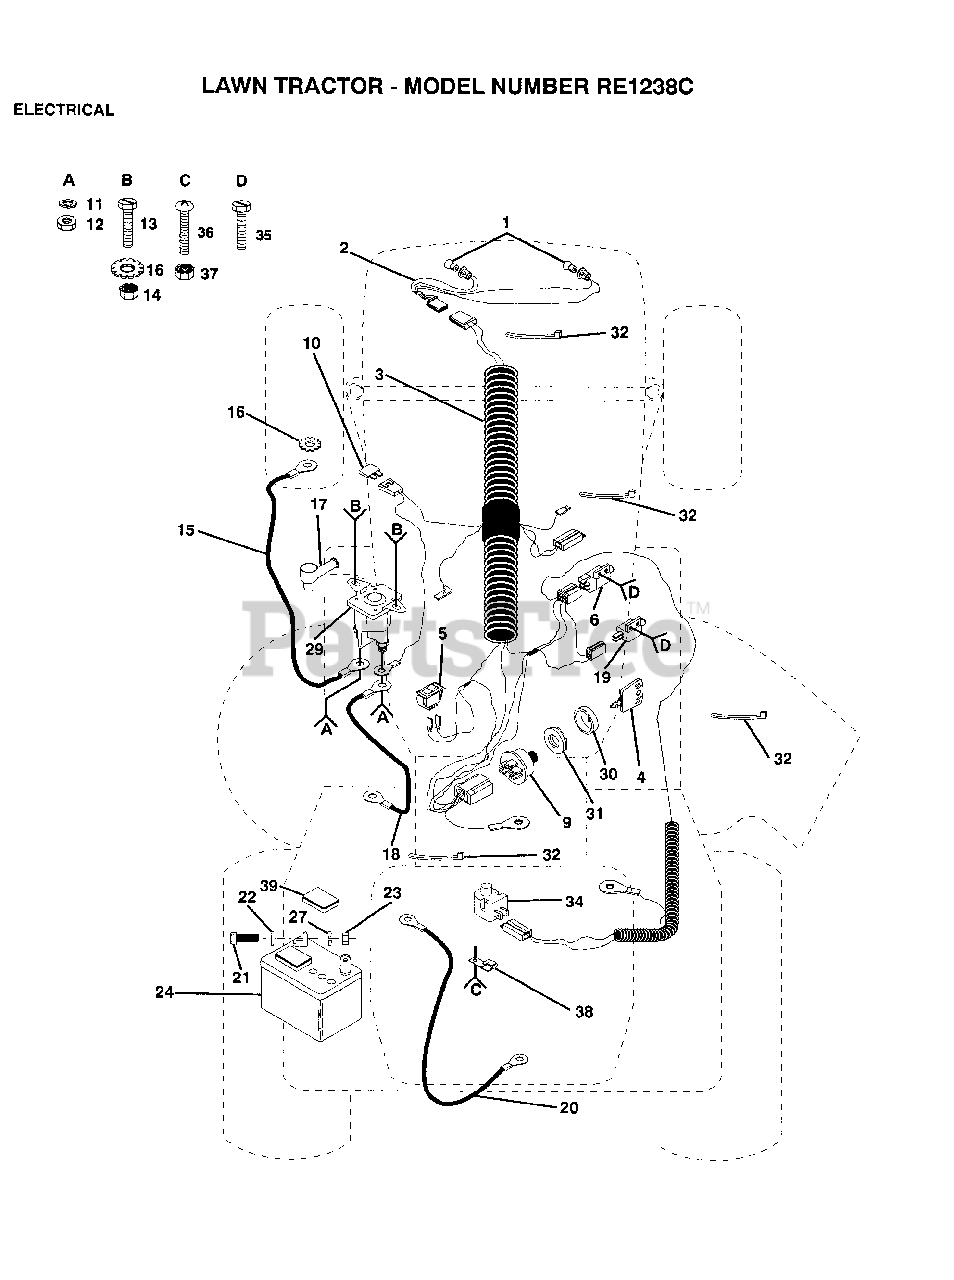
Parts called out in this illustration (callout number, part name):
3	IGN HARNESS
5	SWITCH LT
6	SWITCH-INTER. GT
10	FUSE HYT
12	NUT
13	BOLT
14	NUT
15	"CABLE T, BATTERY"
19	SWITCH INTERLOCKT
20	CABLE T
21	BOLT LT
22	WASHER
27	LOCKWASHER
31	NUT IGNITION
32	WIRE TIE
34	SWITCH SEAT
35	SCREW
37	"NUT,KEPS"
39	"CAP,BATTERY "
